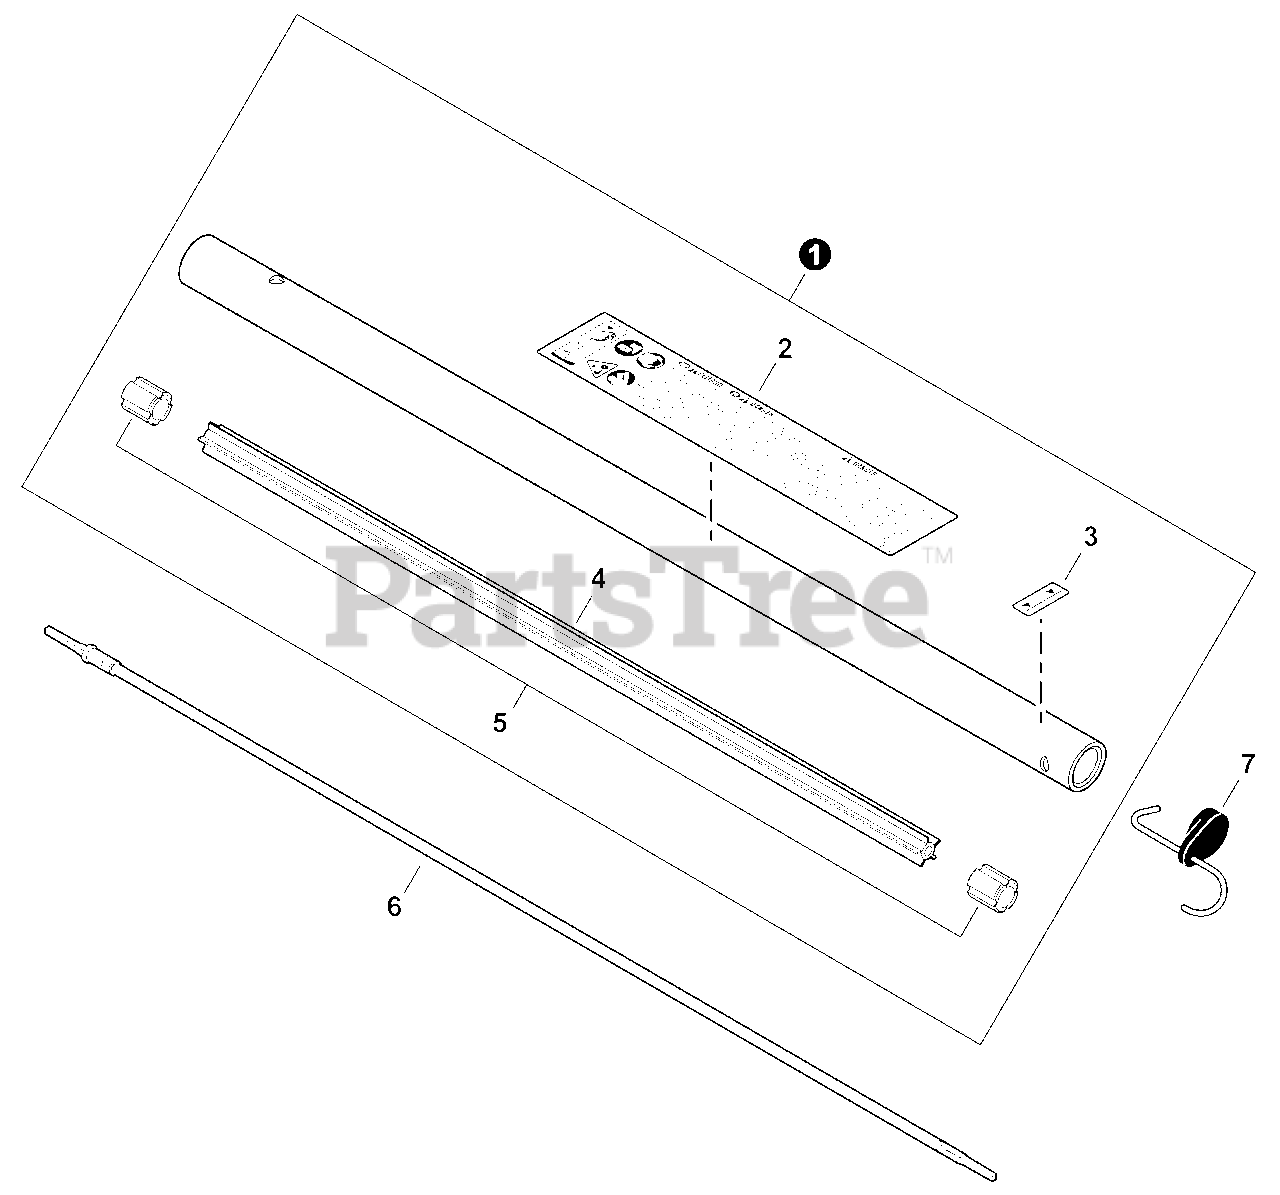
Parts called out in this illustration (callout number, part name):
1	MAIN PIPE ASSY
2	LABEL, CAUTION
3	LABEL - ALIGNMENT
4	LINER - FLEXIBLE
6	DRIVESHAFT - FLEXIBLE
7	HANGER, ATTACHMENT
